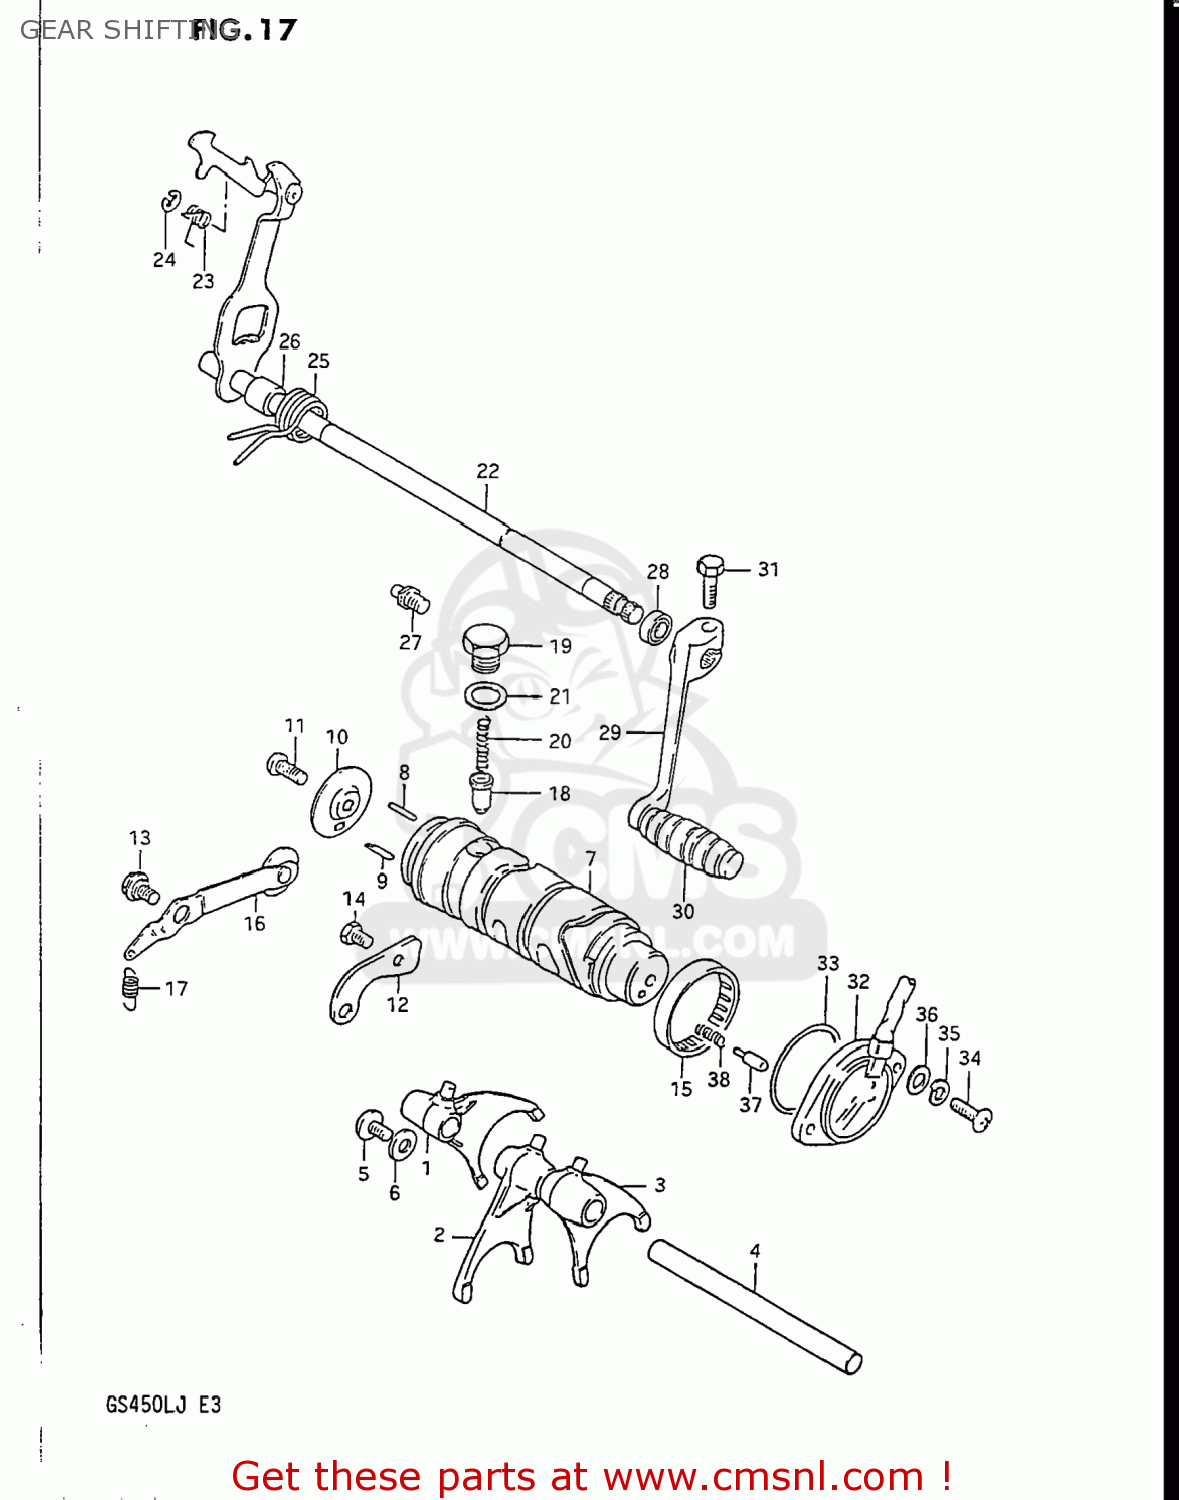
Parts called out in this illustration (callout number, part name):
1	FORK,GEAR SHIFT NO.1
2	FORK,GEAR SHIFT NO.2
3	FORK,GEAR SHIFT NO.2
4	SHAFT,GEAR SHIFT FORK
5	SCREW
6	WASHER
7	CAM,GEAR SHIFT
8	PIN(4X18.5)
9	PIN
10	RETAINER,GEAR SHIFT CAM DR PIN
11	SCREW
12	GUIDE,GEAR SHIFT CAM
13	BOLT
14	BOLT
15	BEARING(40X47X12)
16	STOPPER,GEAR SHIFT CAM NO.1
17	SPRING
18	STOPPER,GEAR SHIFT CAM NO.2
19	HOLDER,SHIFTING CAM STOPPER
20	SPRING
21	GASKET(14X19.2X2) (NAS)
22	SHAFT,GEAR SHIFT
23	SPRING
24	E RING
25	SPRING
26	SPACER(12X20X15.3)
27	STOPPER,GEAR SHIFT CAM
28	OIL SEAL
29	LEVER ASSY,GEAR SHIFT
30	RUBBER,GEAR SHIFT PEDAL
31	BOLT
32	BASE ASSY,GEAR SHIFT TERMINAL
33	O-RING (D:2.4 ID:26.2)
34	SCREW
35	LOCK WASHER
36	WASHER
37	PIN(5X15.5)
38	SPRING
